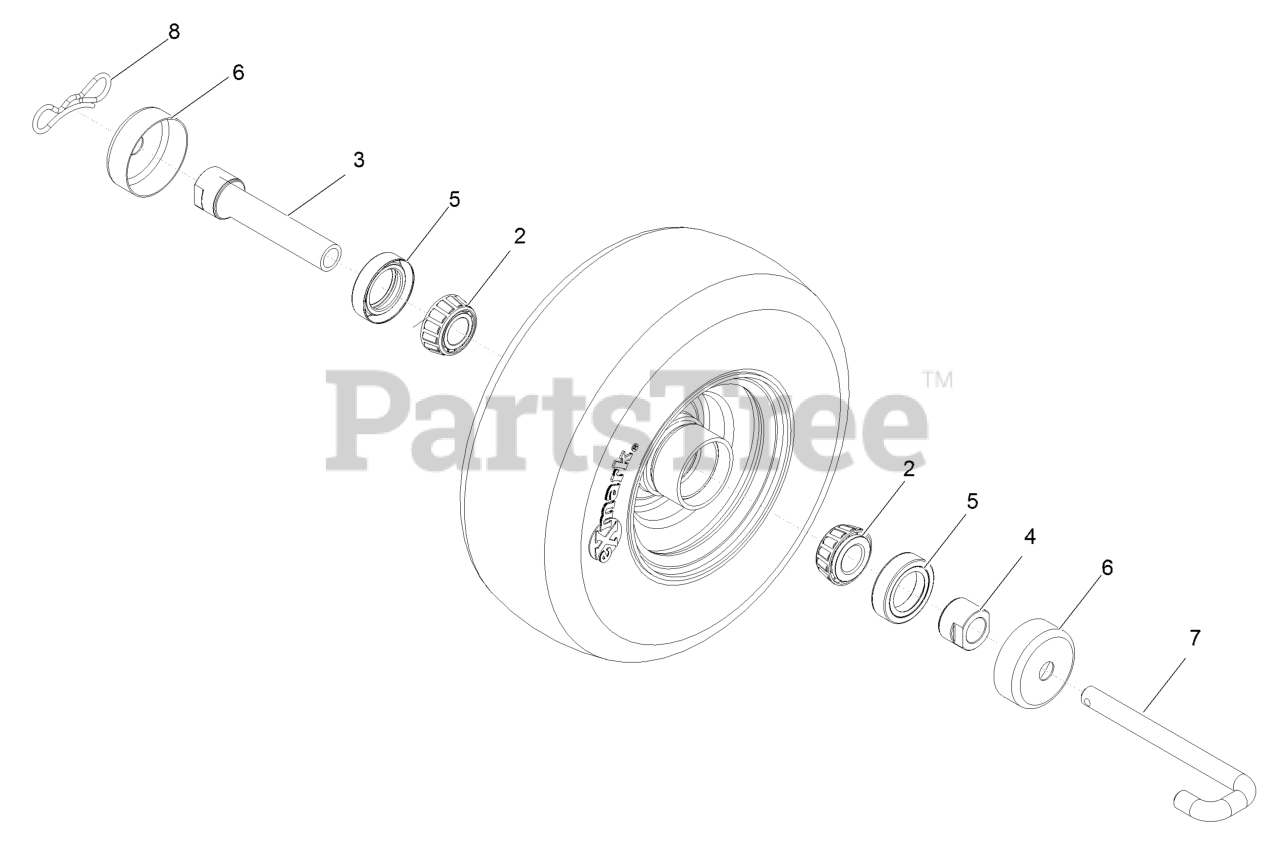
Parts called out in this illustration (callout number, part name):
2	Bearing-Cone Tapered Roller
3	Caster Axle ASM
4	Spacer-Nut
5	Seal-Double Lip
6	Guard-Seal
7	Pin, Caster
8	Pin-Cotter, Locking
